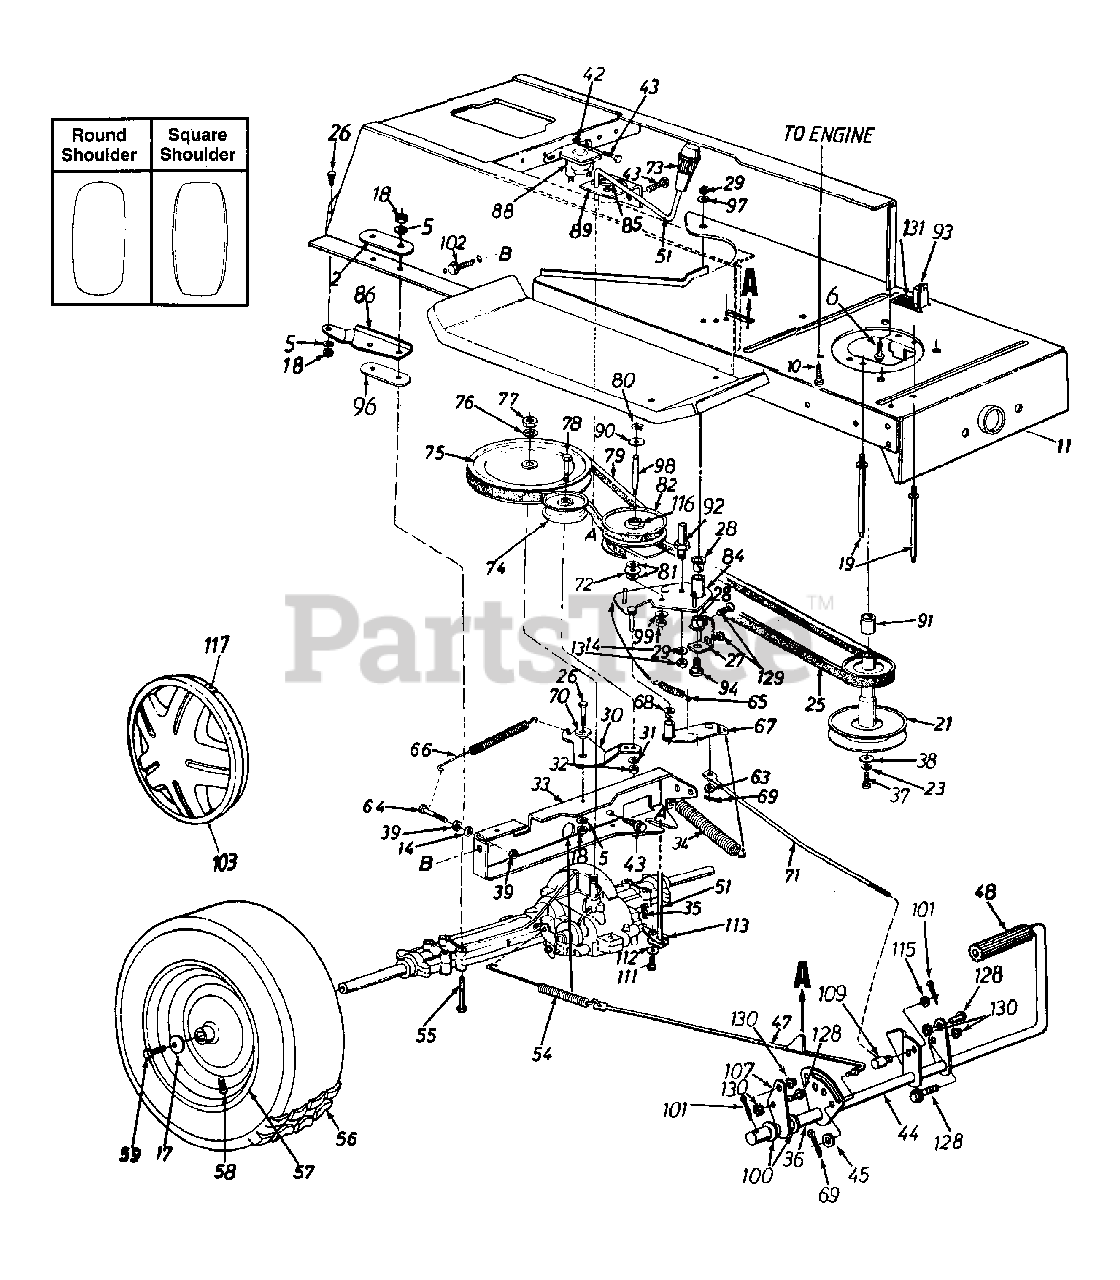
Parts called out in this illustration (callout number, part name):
5	L-Wash. 5/16" I.D.
6	Self-Tap Screw 1/4 x .50
10	Hex TT-Tap Scr. 3/8-16 x 1.5" Lg.
13	Hex Nut 1/4-20 Thd. (Gr. 5)
14	L-Wash. 1/4" I.D.
17	Bell-Wash. .345" I.D. x .88"
18	Hex Nut 5/16-18 Thd. (Gr. 5)
19	Belt Guard Stud 4.75" Lg.
21	Engine Pulley
23	L-Wash. 7/16" I.D.
25	Variable-Speed Belt
26	Hex Bolt 5/16-18 x .75" Lg.
27	Bearing Shaft Bracket Ass'y.
28	Flanged Nyliner Brg. 5/8" I.D. x .88" Lg.
29	Hex Nut 3/8-24 Thd.
31	L-Wash. 3/8" I.D.
32	Hex Nut 3/8-24 Thd.
35	Inter. Cotter Pin
36	Spacer .63" I.D.
37	Cap Screw 7/16-20 x 1.25
38	Flat Washer .450
39	Hex Nut 1/4-28 Thd.
42	Ext. L-Wash. 1/4" I.D.
43	Hex Wash. Hd. S-Tap Scr.1/4-20 x .50" Lg.
47	Brake Rod Ass'y.
48	Foot Pad
51	Shift Lever Ass'y.
54	Ext. Spring .59" O.D. x 7.08"
55	Hex Bolt 5/16-18 x 3.5" Lg.
58	Air Valve
59	Hex Bolt 5/16-24 x .75" Lg.
63	Fl-Wash. .34" I.D. x .68" O.D.
64	Hex Bolt 1/4-28 x 1.25" Lg.
65	Ext. Spring
66	Ext. Spring .62" O.D. x 6.12"
68	Flanged Bearing
69	Cotter Pin 3/32" Dia.
70	Shoulder Spacer .27" Lg.
71	Speed Control Link
72	Truss Bearing .56 Dia. x 1.25"
73	Shift Knob
74	Fl-Idler Pulley 3.12" Dia.
75	"V" Pulley
76	Bell-Wash. .56" I.D. x 1.125"
77	Hex Jam Nut 5/16-18 Thd.
78	Hex Bolt 3/8-24 x 1.75" Lg.
79	Variable Speed Belt
80	Snap Ring .56" Dia.
81	Fl-Wash.
82	Variable Speed Pulley Ass'y.
90	Teflon Washer .565" I.D.
91	Spacer 1" I.D. x 1.25" Lg.
92	Belt Keeper 3" Lg.
93	Safety Switch (Clutch)
94	Shld. Bolt 3/8-24 x 3.12" Lg.
96	Transaxle Spacer
97	Bell-Wash. .38" I.D. x .88"
98	Shaft .56" Dia. x 3.875" Lg.
99	Bell-Wash. .39" I.D. x 1.12"
100	Fl-Wash. .64" I.D. x .94"
101	Cotter Pin 1/8" Dia. x 1.25"
102	Hex Wash. Hd. Scr. 5/16-18 x .62"
103	Hub Cap (Gray)
111	Hex Bolt 1/4-28 x .50" Lg.
112	Bell-Wash. .265" I.D. x .75"
113	Shift Lever Link Ass'y.
115	Fl-Wash. .385" I.D. x .62"
116	Needle Brgs.
117	Spring Clip
128	Hex Wash. TT-Tap Scr. 5/16-18x .75" Lg.
129	Hex Wash. AB-Tap Scr. 5/16-18x .75" Lg.
130	Hex Sems Nut 5/16-18 Thd.
131	Spring Switch
